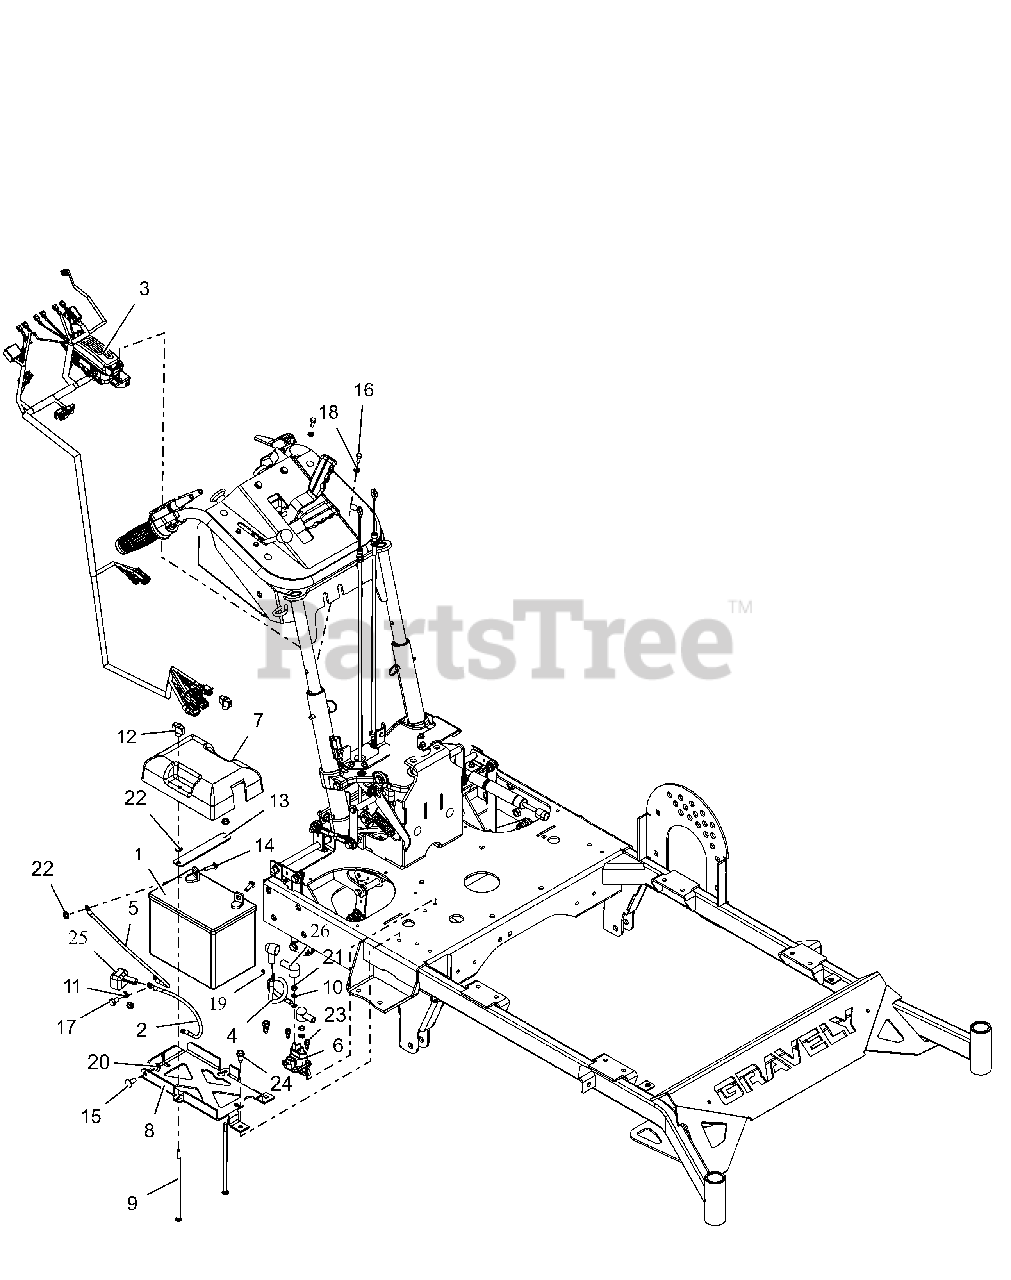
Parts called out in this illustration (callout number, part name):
1	BATTERY, 300 CCA 10U1L
2	CABLE, STARTER 13.00"
3	HARNESS, HYDRO PROWALK
4	CABLE-POSITIVE BATTERY 9.00"
5	CABLE-GROUND .25 X 13.00 X .31
6	SOLENOID, STARTER (SEALED)
7	COVER, BATTERY
8	BRKT, BATTERY TRAY (RED)
9	@BLT-RDHDSQNK .25-20X7.00 G2YZ
10	@WSHR-LK-EXT.262X.502X.026YWZC
11	@WSHR-LK-EXT.326X.599X.031YWZC
12	KNOB, WING - .25-20 UNC
13	STRAP, BATTERY
14	@BLT-RDHDSQNK .25-20X1.00 G5YZ
15	@BLT-RHDSSQNK .31-18X.75 G5YZ
16	@BLT-HEX M6-1X16 YWZC
17	@BLT-HEX M8 X 1.25X14 YWZC
18	@WSHR-LK .25X.062 REG YWZC
19	NUT, HEX-JAM M6-1.0 G8.8 ZCC
20	@NUT-LK-CTR-FLG .31-18 YZ GR F
21	NUT-HEX M6X1.0 YWZC
22	@NUT-SPNLK-FLG .25-20 YWZC
23	SCR-TAP .25-20X.50 HWH TR YWZ
24	@SCR-TAP .31-18X.75 HWH TR YWZ
25	INSULATOR
26	BOOT, EYELET TERMINAL
